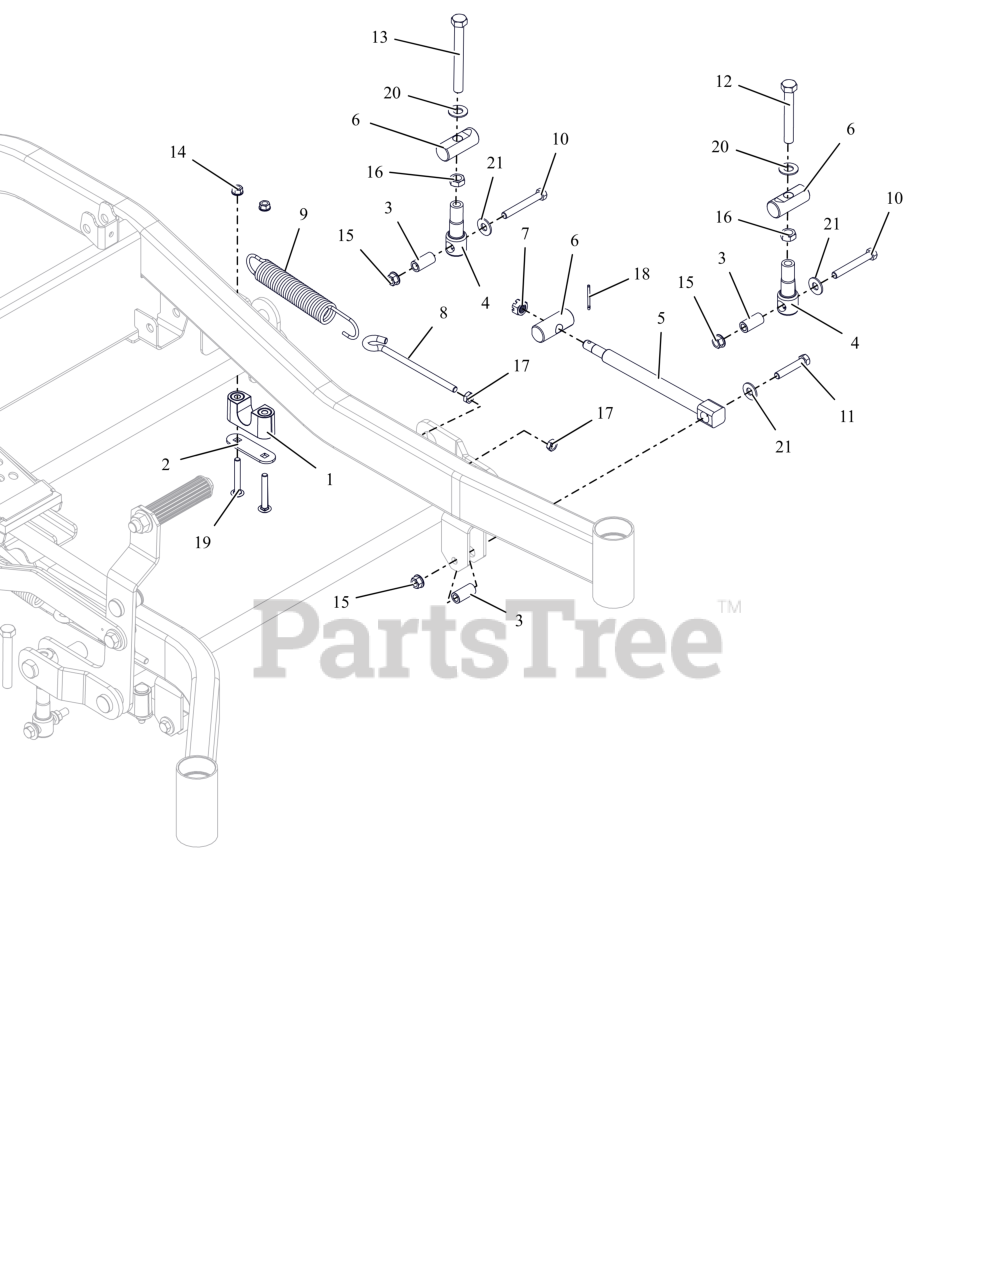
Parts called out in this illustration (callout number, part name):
1	ASM-BUSHING, DECK LIFT
2	PLATE, BEARING SUPPORT
3	SPACER, DECK LEVELING
4	LINK, DECK LIFT FORMED
5	DRAG,LINK-HD
6	PIN, DECK LIFT
7	NUT-SL .50-13
8	BOLT,.38-16 X 5.25-.62 DIA EYE
9	SG-TENS .162X1.25X8.25 WLD 25
10	BLT, HEX .38-16X2.75 G8 ZCC
11	BLT,HEX .38-16X2.00 G5 ZCC
12	BLT, HEX .50-13X3.50F G5 ZCC
13	BLT, HEX .50-13X4.50F G8 ZCC
14	NUT,LK-CTR-FLG .31-18 GF ZCC
15	NUT-LK-TOP-FLG .38-16 ZC120
16	NUT-JAM .500-13 G2 ZCC
17	NUT-JAM .375-16 G2 ZCC
18	PIN,CTR.12X1.25EXTPRSQCT ZC120
19	BLT, RHSSN.31-18X2.25 G5 ZCC
20	WSHR, FLT .557X1.040X.102 ZCC
21	WSHR,FLT .438X1.00X.083 ZCC
